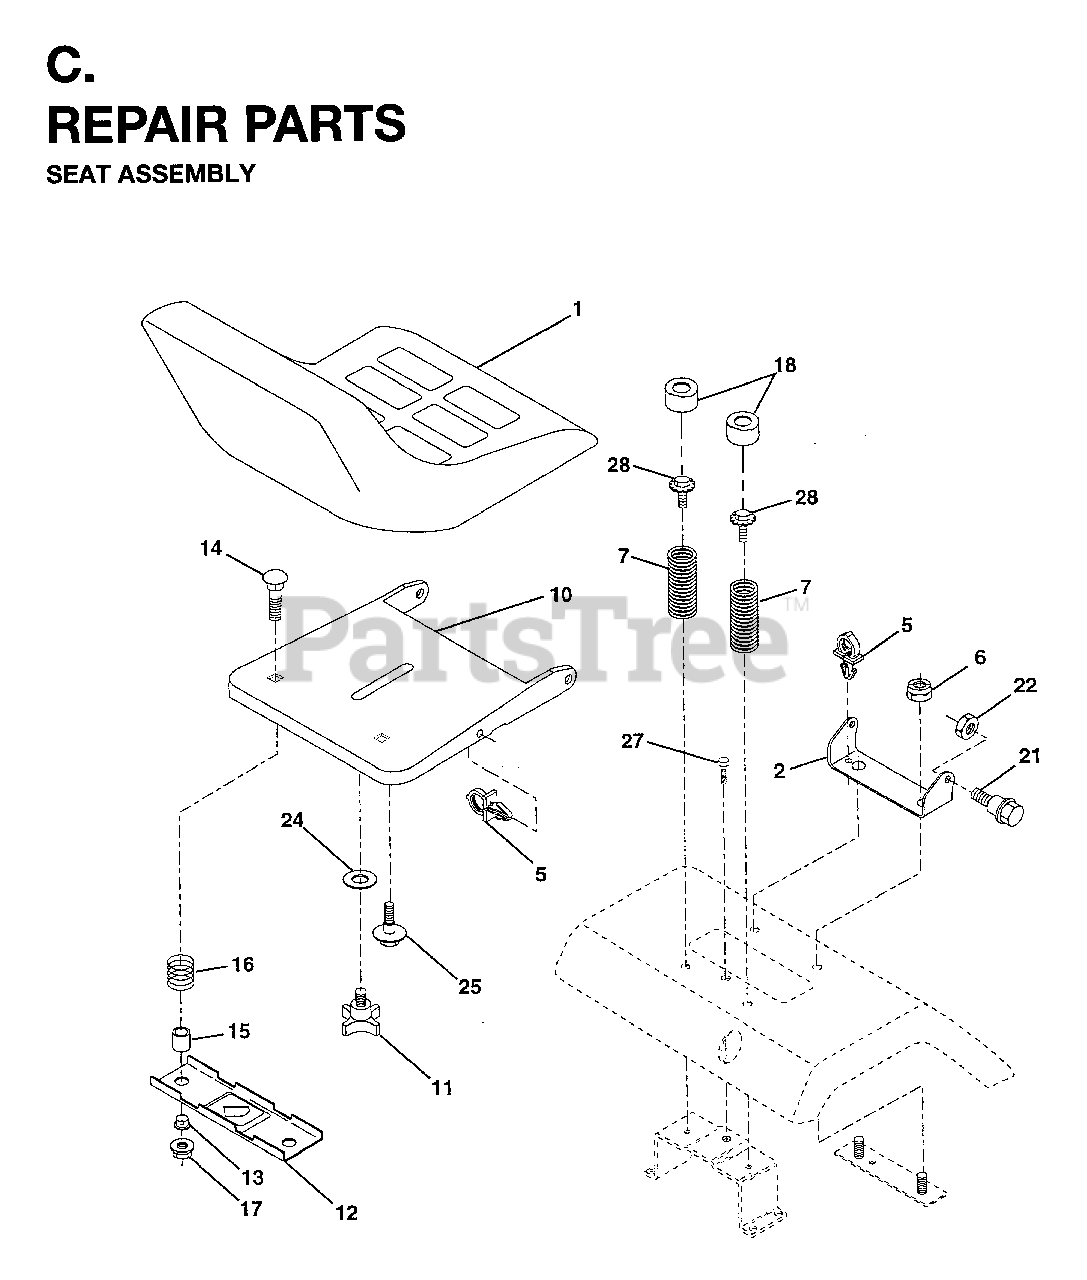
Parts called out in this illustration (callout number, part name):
1	SEAT
2	SEAT PIVOT BRKT
5	PUSH CLIP
6	LOCKNUT
7	SPRING COMPRESSION
10	SEAT PAN
11	KNOB 1/2" YT
12	BRKT SWITCH
14	BOLT CARRIAGE 1/4-20X1 3/8
15	SPACER SPLIT
16	SPRING COMPRESSED
17	NUT T
18	CAP SPRING
22	LOCKNUT
25	BOLT,SHOULD
28	BOLT
